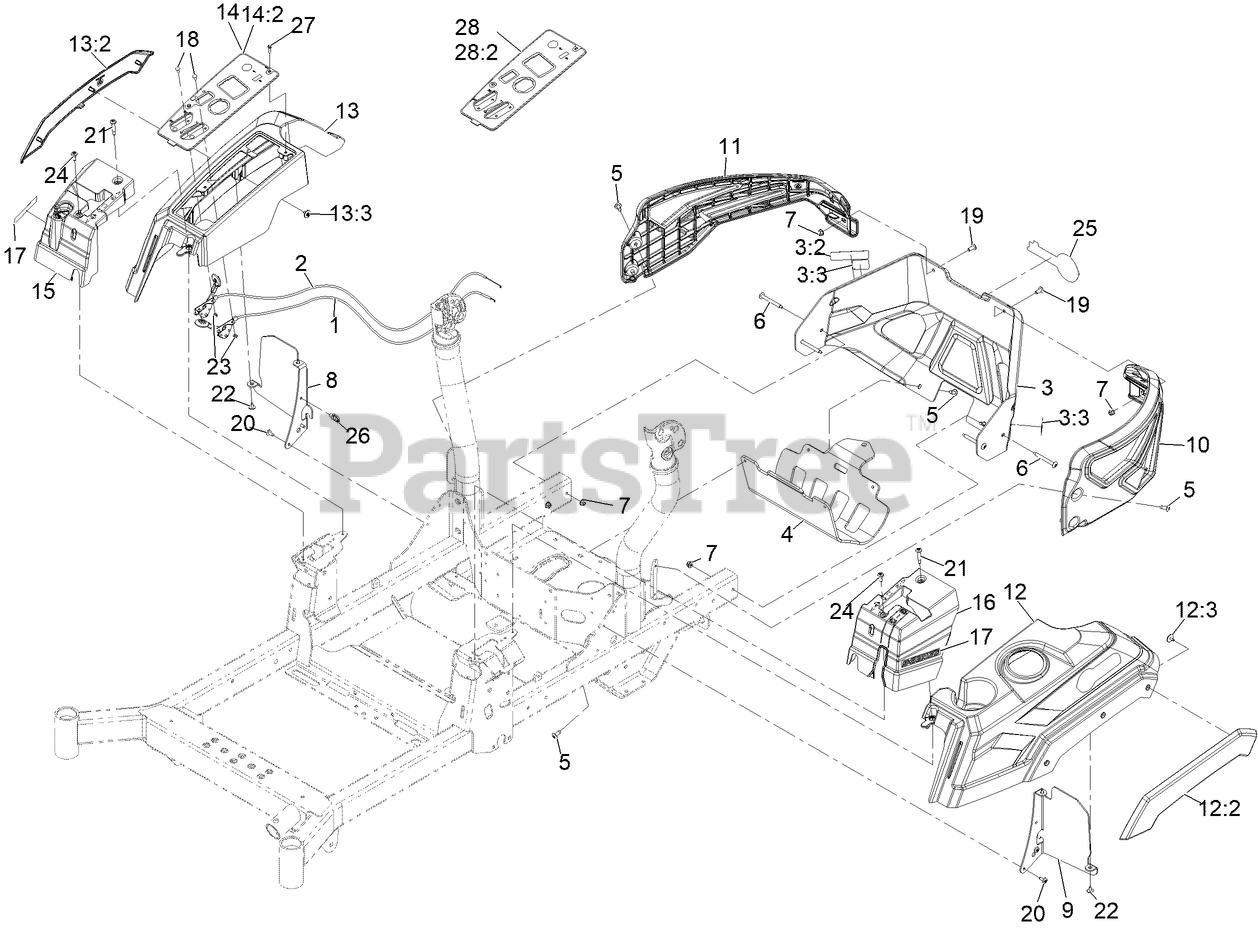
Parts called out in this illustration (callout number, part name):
1	CABLE-CONTROL, THROTTLE
2	CABLE-CONTROL, CHOKE
3	ASM, Rear Guard W/ Decals
3:2	DECAL-ARRESTOR, SPARK
3:3	DECAL-WARNING
4	Guard, Muffler
5	SCREW, TAPTITE
6	SCREW-TORX
7	NUT-HF, NI
8	Bracket, Pod, Rt
9	Bracket, Pod, Lt
10	GUARD, UPPER, LT
11	GUARD, UPPER, RT
12	ASM, Pod Lt
12:2	Fender, Lt
12:3	Screw-Torx
13	ASM, POD RT
13:2	Fender, Rt
13:3	Screw-Torx
14	ASM-Control Panel W/Decal
14:2	DECAL-CONTROL PANEL
15	Cover, Motion Control, Rt
16	Cover, Motion Control, Lt
17	DECAL-S-SERIES
18	BOLT-CARR
19	SCREW-TORX
20	SCREW-TORX
21	SCREW-SHOULDER
22	SCREW-TORX
23	NUT-LOCK, NI
24	SCREW-SHOULDER
25	DECAL, EXMARK LOGO
26	CLIP-TIE
27	Screw-Plastic, HWH
28	ASM-Control Panel W/Decal
28:2	Decal-Control Panel
